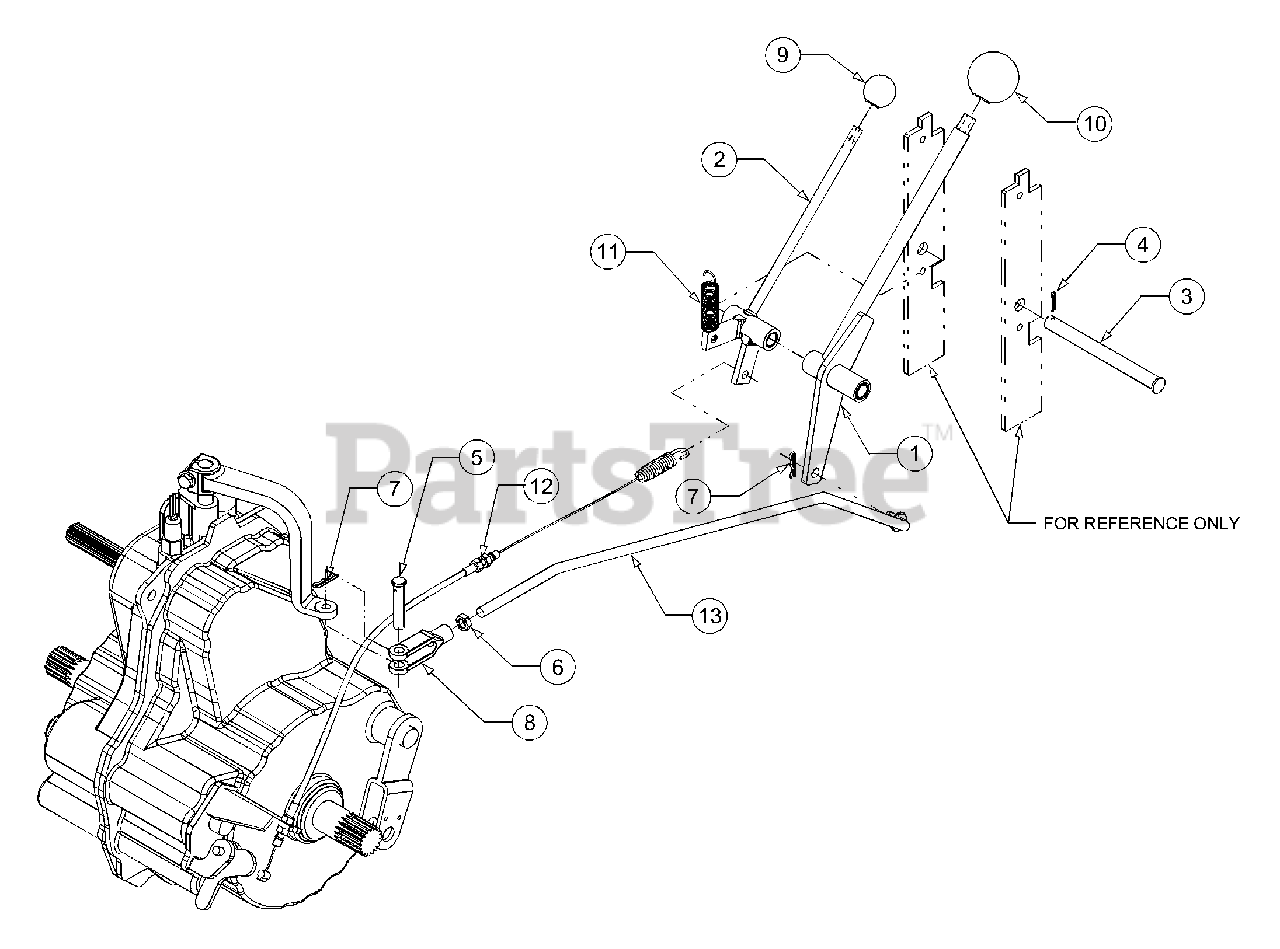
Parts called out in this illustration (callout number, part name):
1	Lever Assembly, Transmission
2	Shifter Assembly, Differential Lock
3	Pin, Clevis, .50 x 5.375
4	Pin, Cotter
5	Pin, Clevis, .375 x 2.0
6	Nut, Jam, 3/8-24
7	Pin, Cotter, .072 x 1.13
8	Clevis, Adjustment
9	Knob, Ball
10	Knob, Ball
11	Spring, Extension, .637 x 2.972
12	Control Cable, Differential Lock
13	Shifter Rod, Transmission
